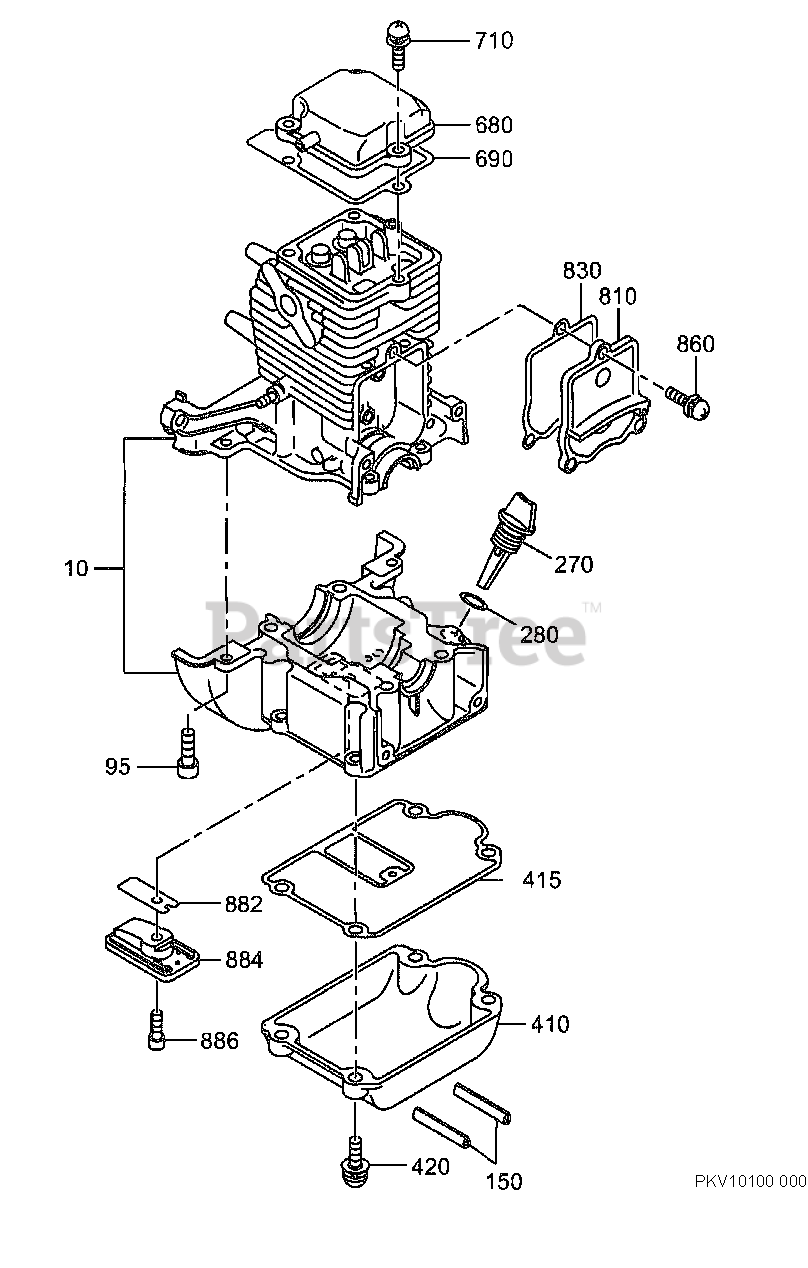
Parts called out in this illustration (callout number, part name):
10	CYLINDER BLOCK SET
95	SOCKET HEAD BOLT
150	GUARD, CASE OIL
420	SCREW AND WASHER AY
680	ROCKER COVER CP
690	GASKET, ROCKER COVER
710	SCREW AND WASHER AY
810	COVER, CAMGEAR
830	GASKET, COVER CAMGEAR
860	SCREW AND WASHER AY
884	RETAINER PLATE
886	SOCKEY HEAD BOLT
